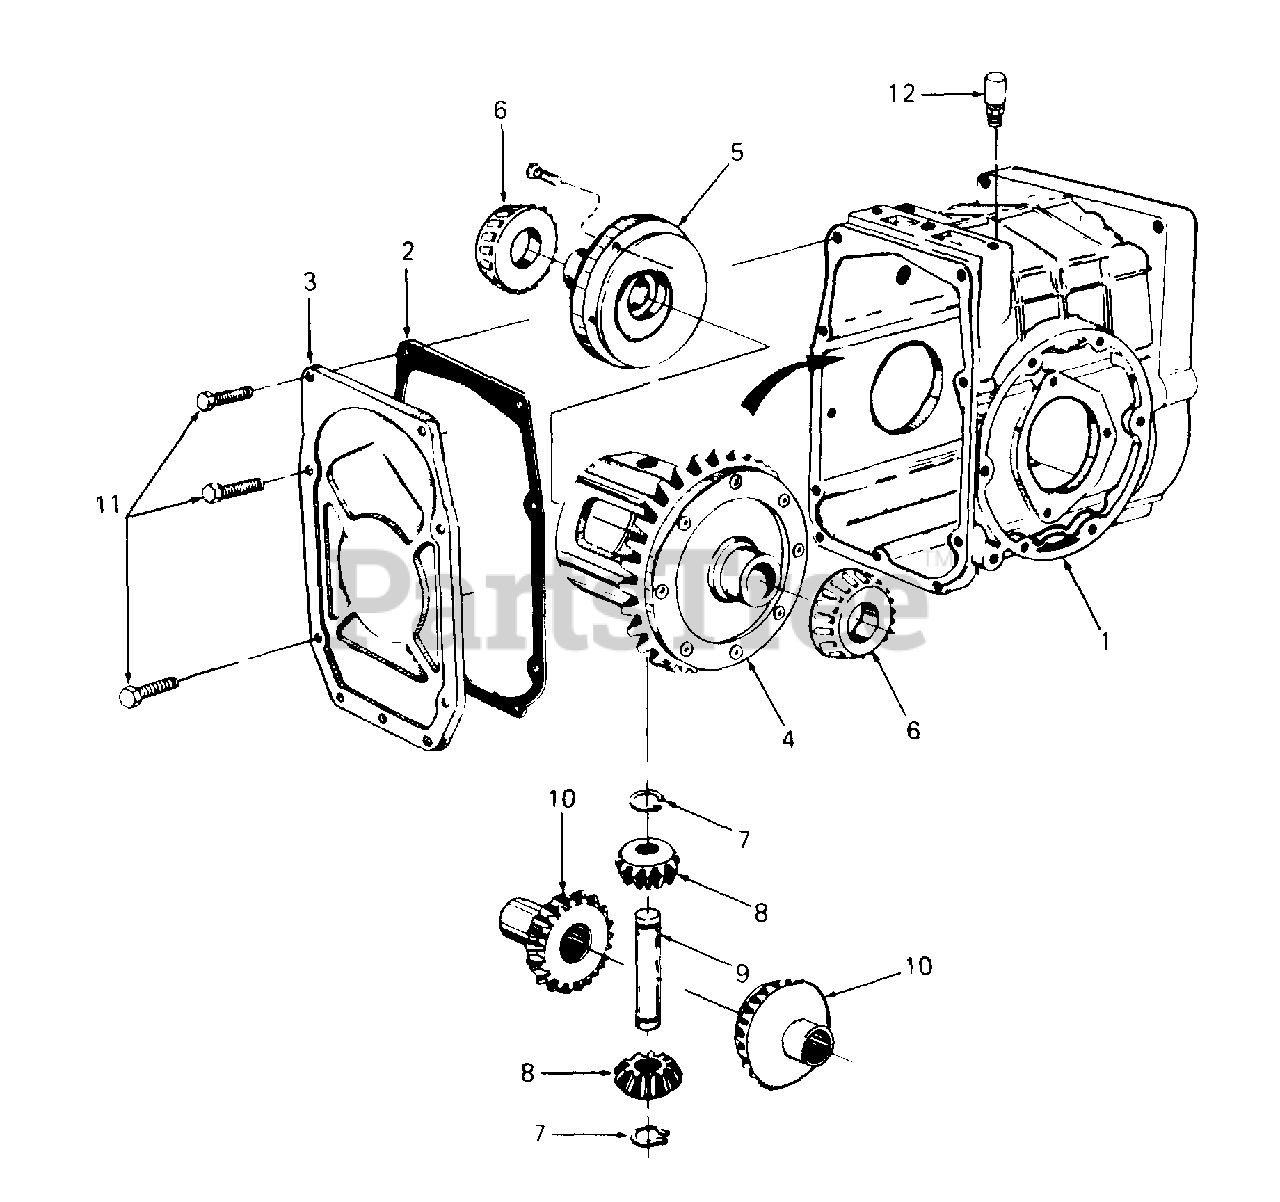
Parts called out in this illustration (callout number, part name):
1	Housing Assy, Rear Transaxle
2	Gasket, Rear Cover
3	Plate, Rear Cover
4	Gear Assy, Ring w/Case
5	Plate, Differential Flange
6	Cone, Roller Brg
7	Ring, Retaining, 11/16
8	Gear, Pinion - 10T
9	Shaft, Cross
10	Gear, Side - 16T
11	Bolt, Hex Patch, 3/8-16 x .62 Lg GR5
